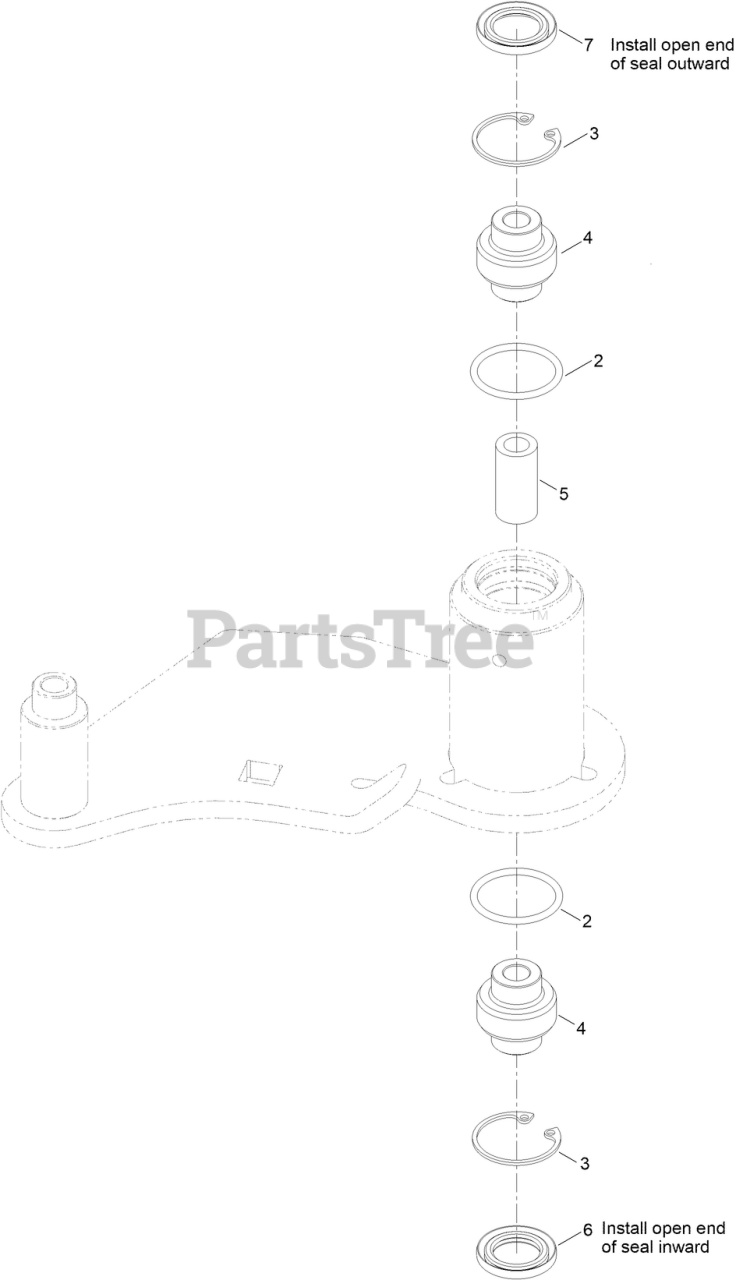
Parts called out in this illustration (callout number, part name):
2	O-RING
3	RING-SNAP
4	BEARING-SPHERICAL
5	SPACER
6	SEAL-LIP, DOUBLE
7	SEAL-LIP, SINGLE
